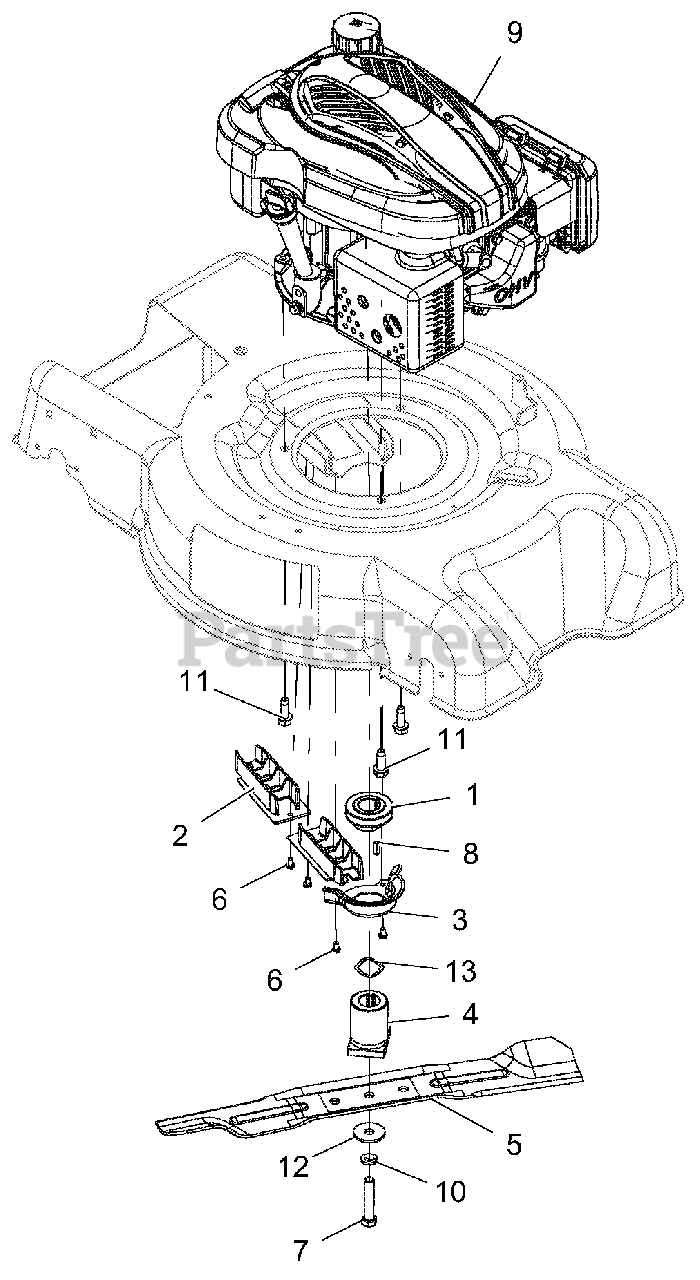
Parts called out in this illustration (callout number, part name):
1	PULLEY, GROUND DRIVE, LM
2	GUIDE, BELT INNER
3	GUIDE, BELT CRANK
4	ADAPTER, BLADE
5	BLADE, MOWER 21" HIGH LIFT
6	SCR-TAP 10-24X.375 PRE-COAT 80
7	@BLT-HEX .4375-20X2.25 GR8 YWZ
8	KEY-SQ .188X.188X.625
9	ENGINE, LONCIN 159CC VERT. ES
10	@WSHR-LK .44X.109 REG YWZC
11	@SCR-TAP .38-16X1.00 HWH TR YZ
12	WSHR-FL-STL .4375X1.50X.125 YZ
13	WASHER - WAVE 1.09X1.37X.016
